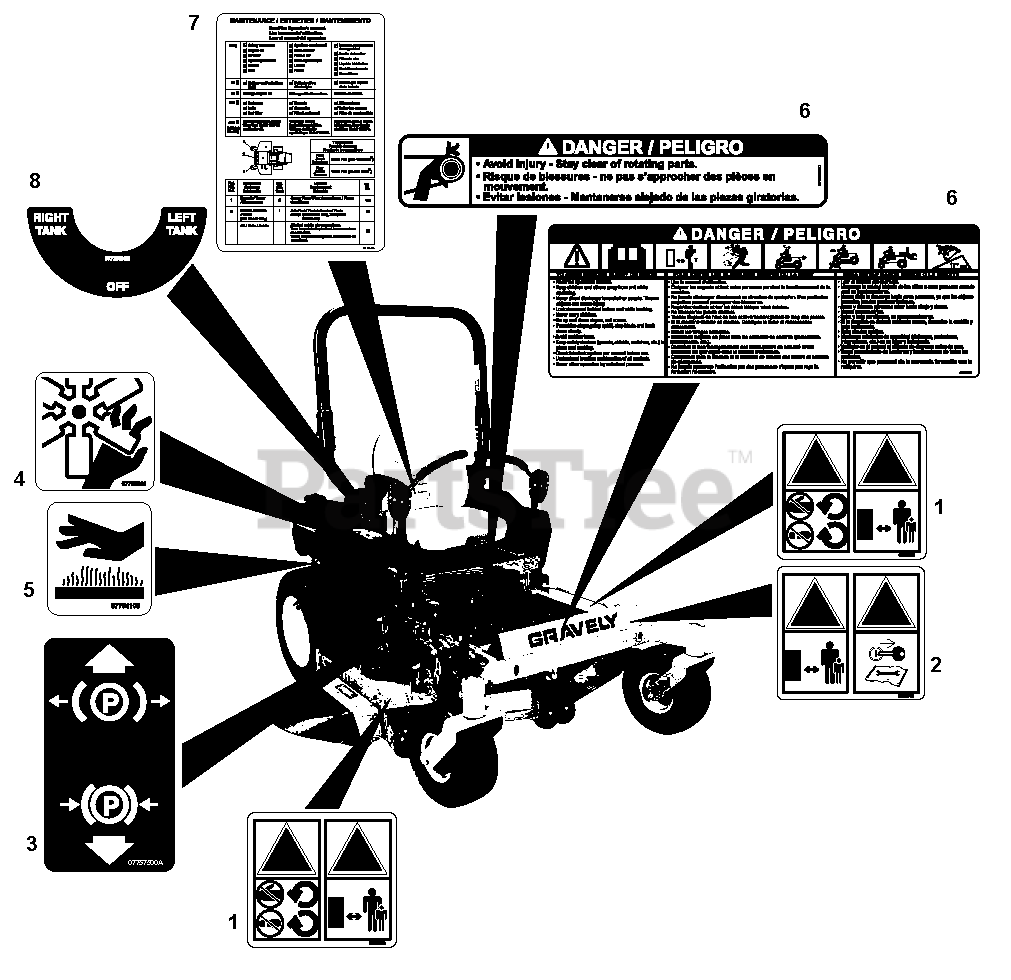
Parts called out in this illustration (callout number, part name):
1	Decal, CE Deck
2	Decal, CE Caution
3	Decal, Parking Brake Lever
4	Decal, Danger Fan
5	Decal, Hot Surface
6	Decal, Common Danger/Fuel
7	Decal, Maintenance Instructions
8	Decal, Fuel Control Valve
